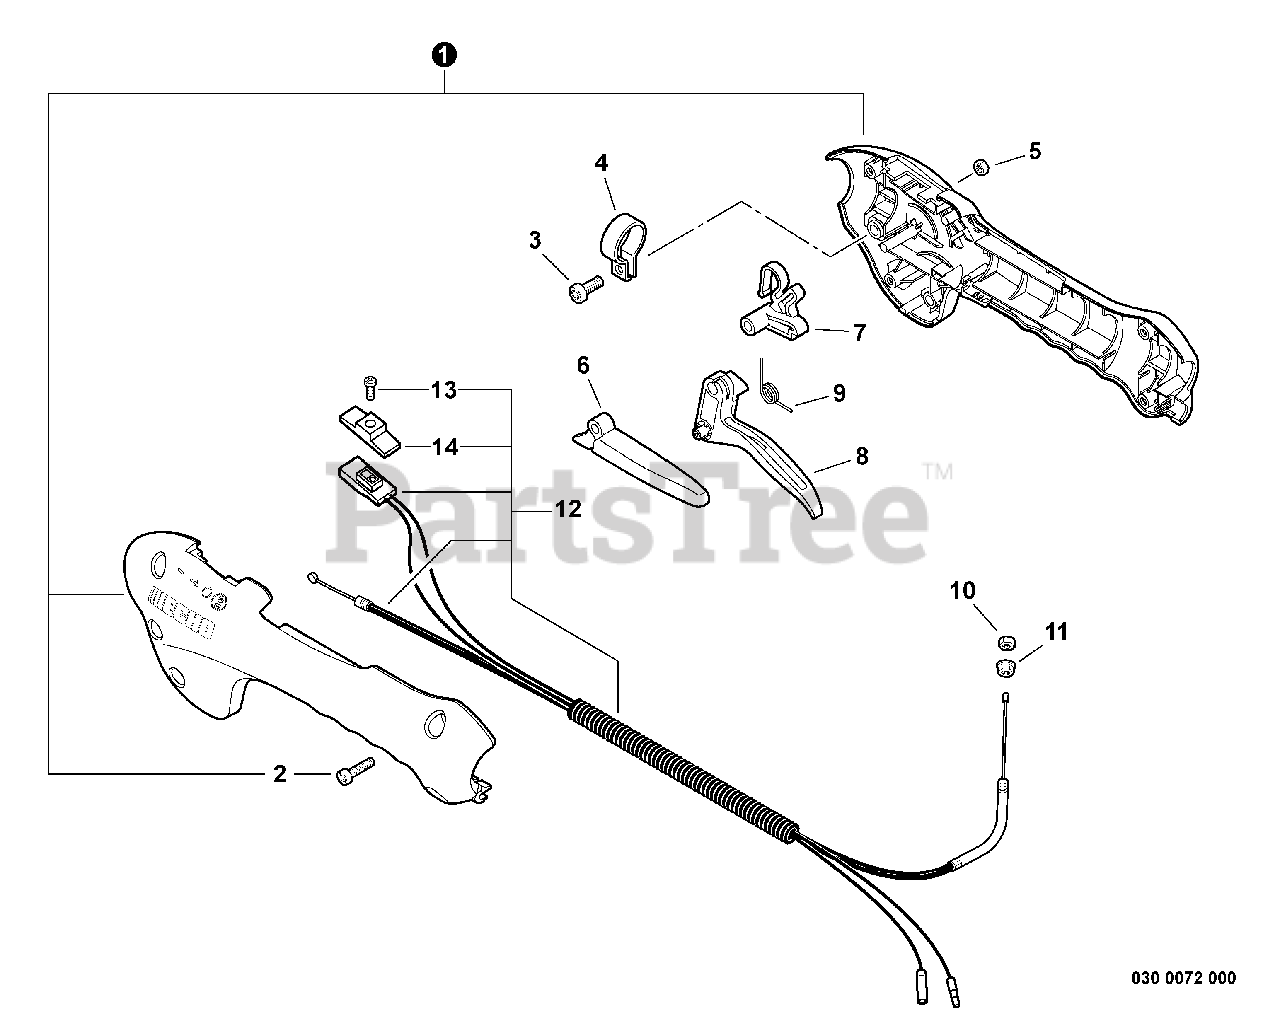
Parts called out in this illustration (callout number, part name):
1	CONTROL HANDLE SET
2	BOLT, TORX 4×16
3	BOLT, TORX 5×16
5	NUT M5
6	LEVER, THROTTLE LOCKOUT
7	LOCKOUT, THROTTLE
8	TRIGGER, THROTTLE
9	SPRING, TRIGGER
11	NUT, FLANGE M6×1
12	CABLE ASSY, CONTROL
13	SCREW 3×10
14	KNOB, SWITCH - ORANGE
